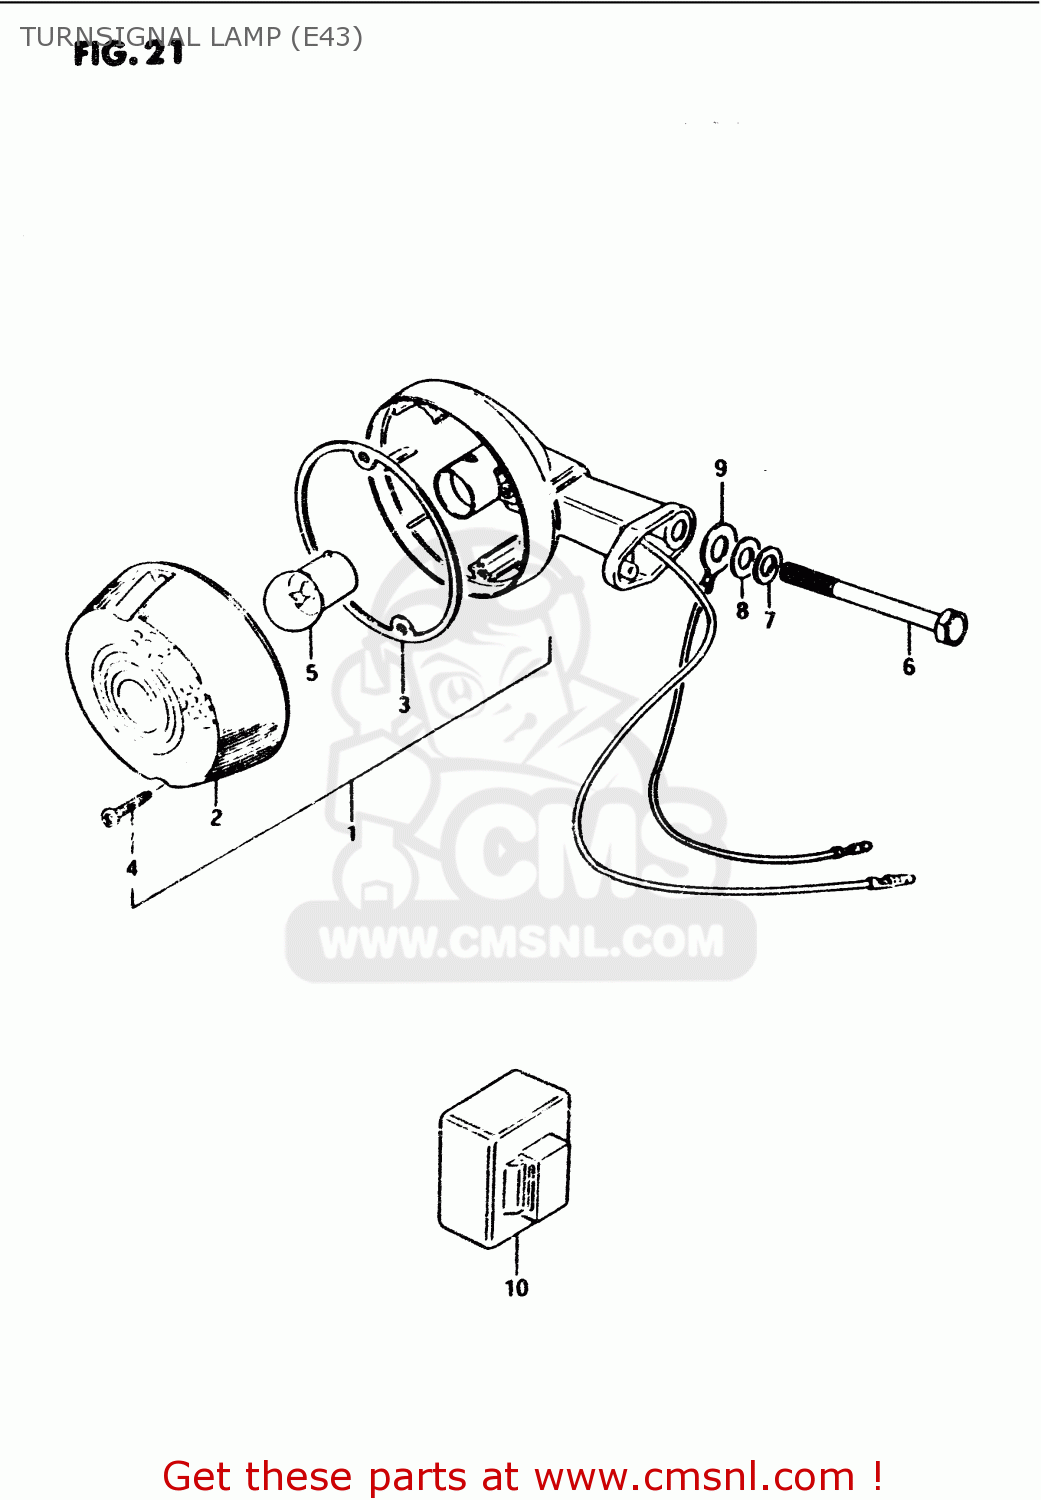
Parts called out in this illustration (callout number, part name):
1	BLINKLYS
2	LENS,TURNSIGNAL
3	GASKET (NAS)
4	SCREW
5	BULB(6V8W,STANLEY,A4115)
6	BOLT(6X65)
7	WASHER,LOCK
8	WASHER
9	LEAD WIRE,EARTH
10	RELAY,TURN SIGNAL
